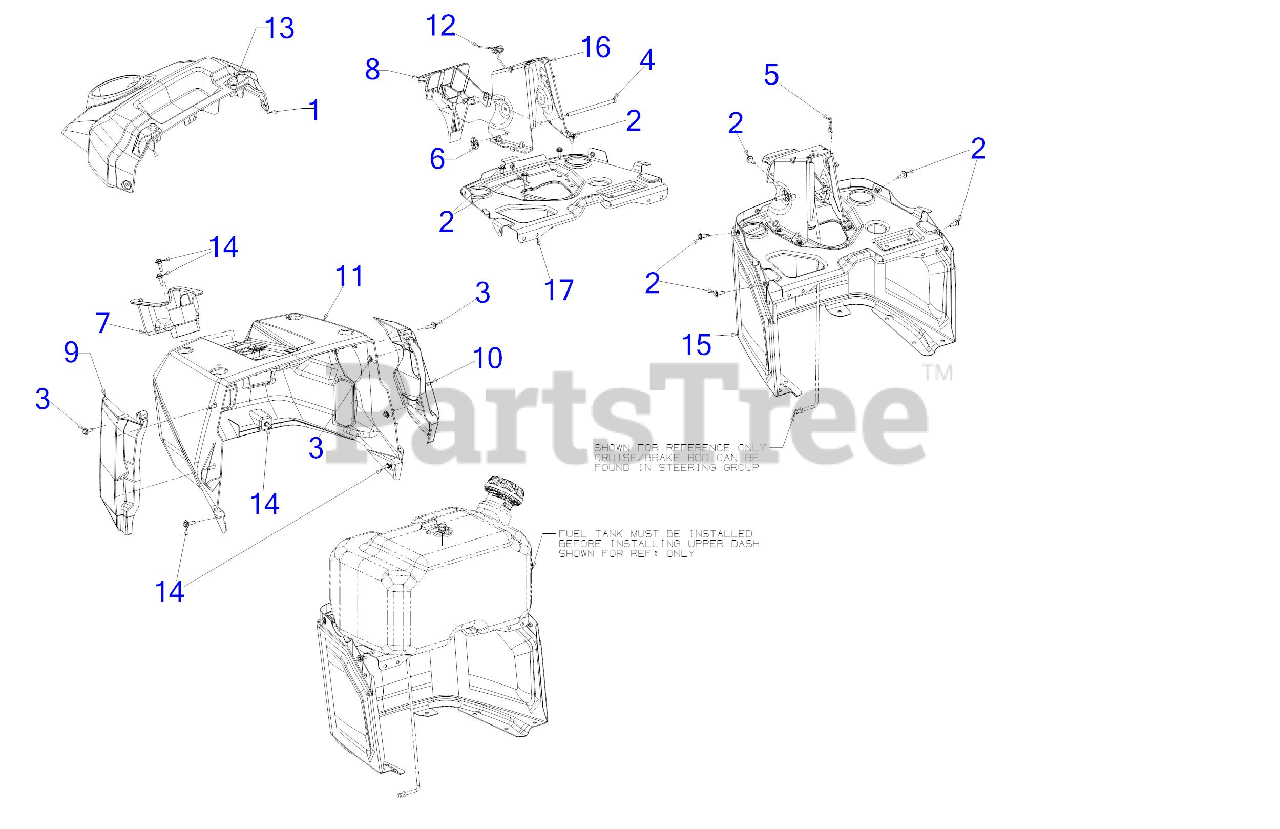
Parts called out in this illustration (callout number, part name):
1	UPPER DASH CAP
2	SCREW M6-1 x .625
3	SCREW 1/4-10 x .750
4	HINGE PIN .25 x 4.50
5	BOW TIE COTTER PIN 1/4-5/16
6	PUSH ON NUT
7	STEERING SHAFT BEARING
8	CRUISE/BRAKE DASH LEVER
9	DASH SIDE CAP (RH)
10	DASH SIDE CAP (LH)
11	UPPER DASH
12	TORSION SPRING .330 ID
13	BUMPER, .62 DIA x .3
14	SHOULDER SCREW M6-1 .368 X.115
